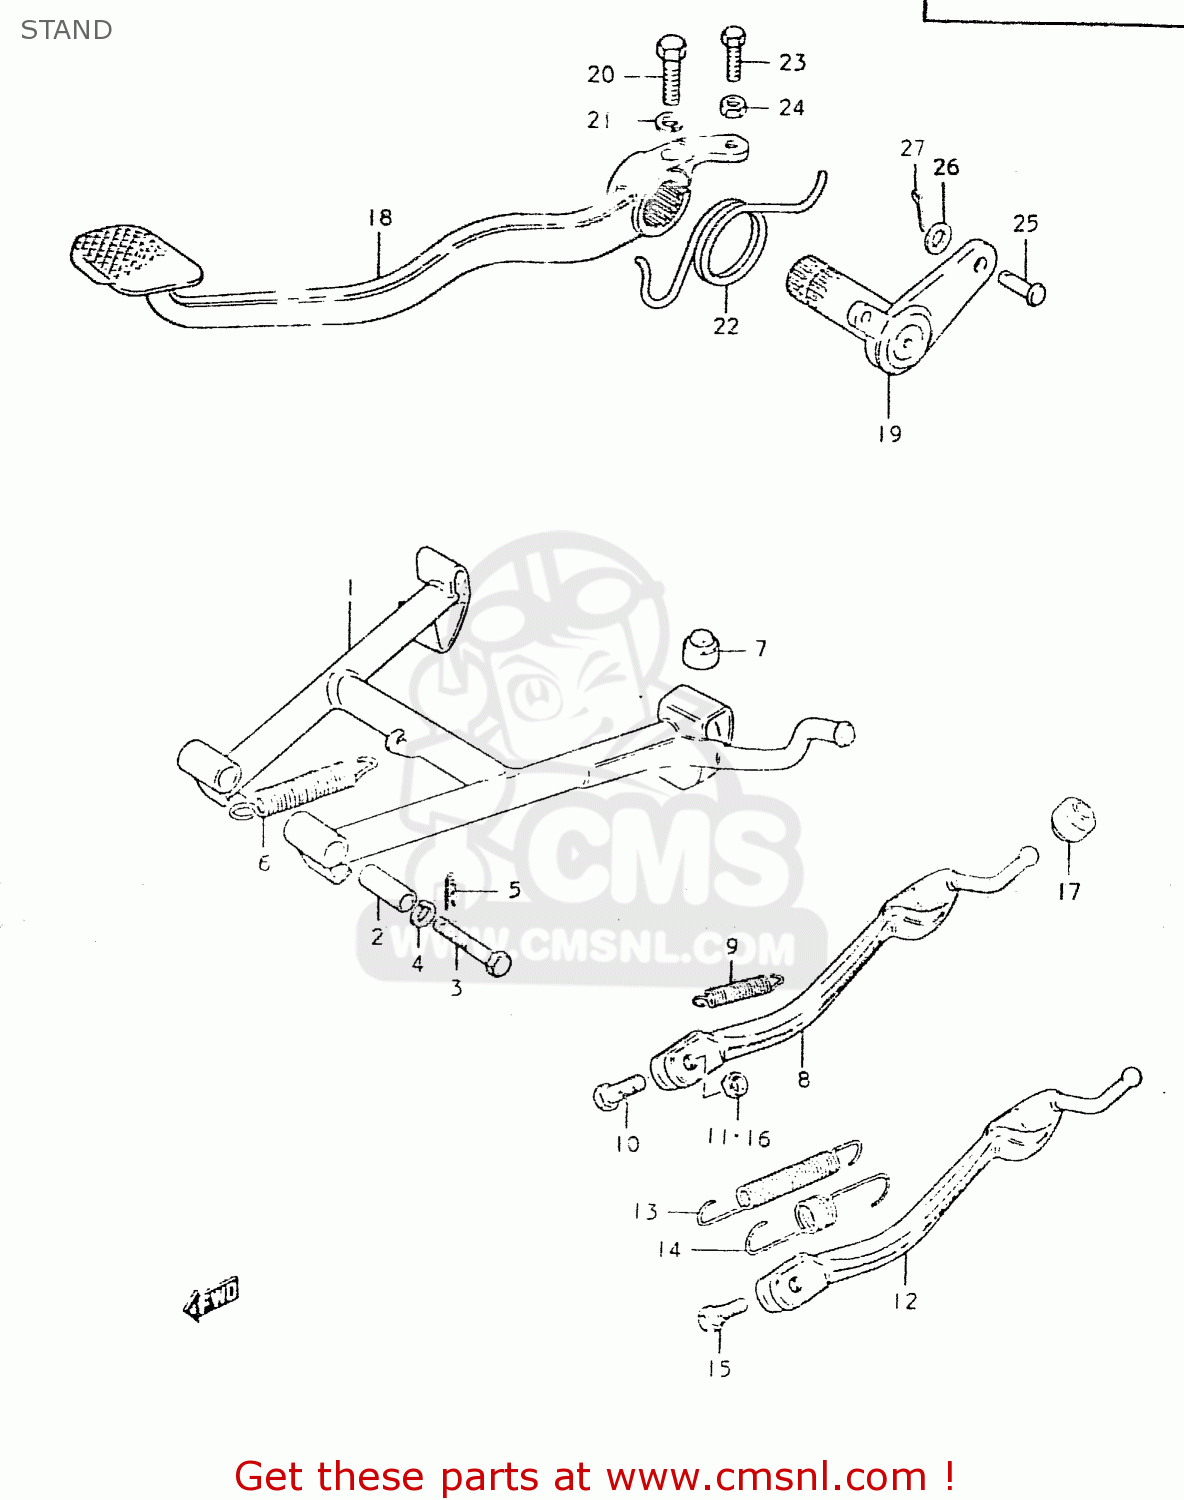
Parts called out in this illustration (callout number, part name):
1	STAND,CENTER
2	SPACER(10X16X38.8)
3	BOLT
4	LOCK WASHER
5	CLIP
6	SPRING
7	CUSHION
8	STAND,SIDE
9	SPRING
10	BOLT(10X30)
11	NUT
12	STAND, PROP
13	SPRING
14	SPRING, OUTER
15	BOLT
16	NUT
17	CUSHION
18	PEDAL,BRAKE
19	ARM,BRAKE PEDAL ROD
20	BOLT
21	LOCK WASHER
22	SPRING
23	BOLT
24	NUT
25	PIN
26	WASHER
27	PIN
